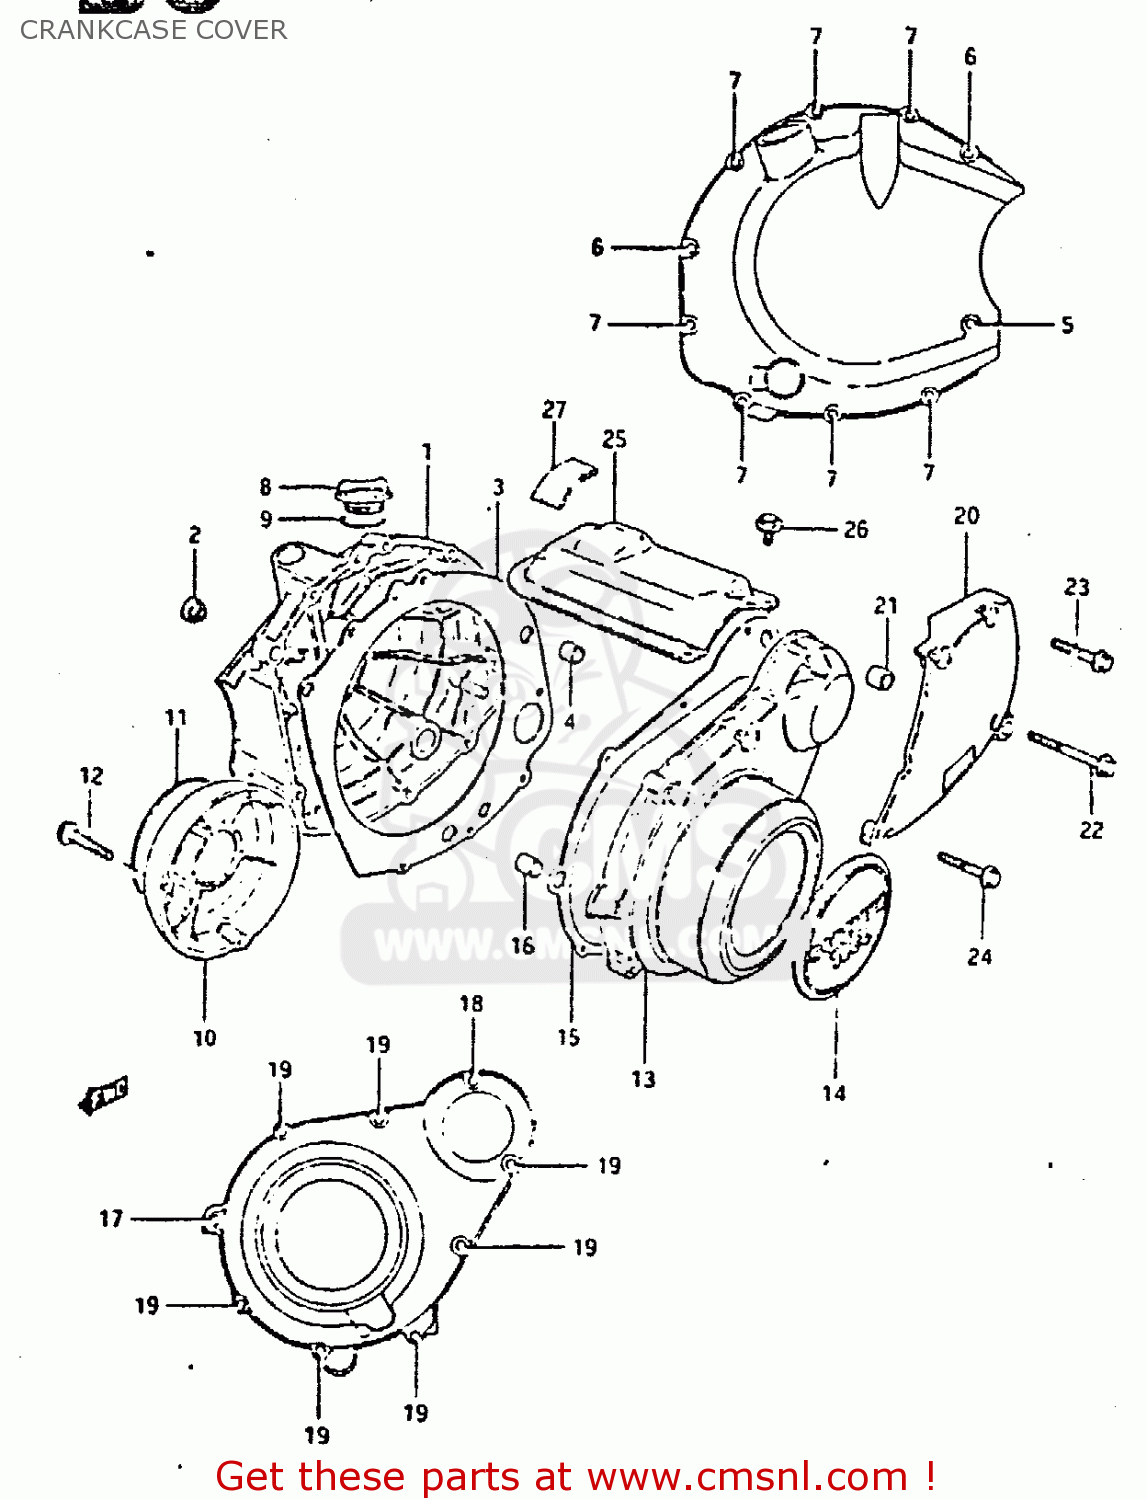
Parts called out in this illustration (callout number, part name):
1	COVER,CLUTCH
2	LENS,OIL LEVEL CHECK
3	GASKET,CLUTCH COVER (MCA)
4	PIN
5	BOLT (6X65)
6	BOLT (6X40)
7	BOLT (6X30)
8	PLUG SET
9	O-RING
10	COVER,CONTACT BREAKER
11	EMBLEM
12	BOLT (5X30)
13	COVER,MAGNETO
14	EMBLEM,MAGNETO COVER
15	GASKET,MAGNETO COVER (MCA)
16	PIN
17	BOLT
18	BOLT (6X35)
19	BOLT (6X30)
20	COVER,SECONDARY DRIVE
21	PIN
22	BOLT (6X40)
23	BOLT (6X30)
24	BOLT
25	COVER,STARTER MOTOR
26	BOLT
27	DAMPER,STARTER MOTOR CLUTCH
